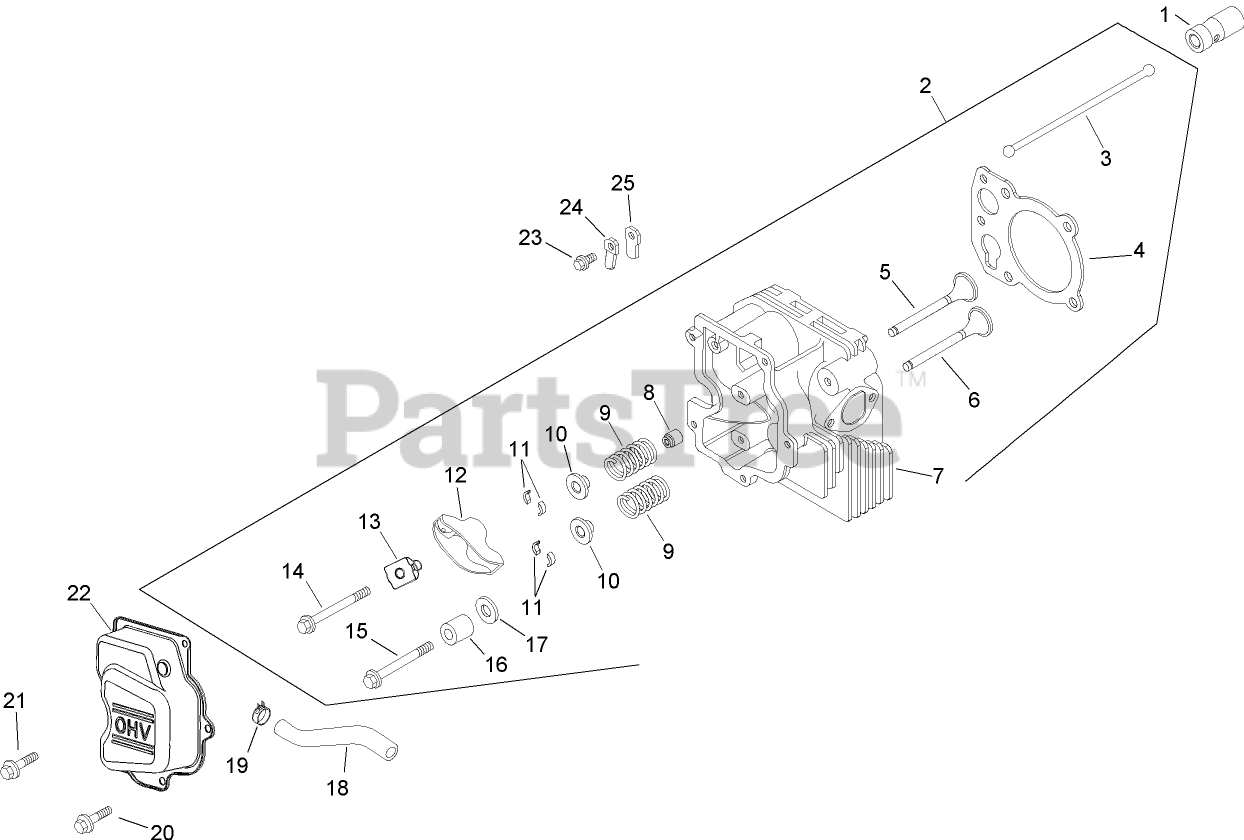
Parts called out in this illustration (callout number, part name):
1	Lifter-Valve
2	Cylinder Head Kit (Incl. Ref. No. 3-17)
3	Rod-Push
4	Gasket-Head, Cylinder
5	Valve-Intake (STD)
6	Valve-Exhaust (STD)
7	Head-Cylinder
8	SEAL-STEM, VALVE
9	Spring-Valve
10	CAP-SPRING, VALVE
11	RETAINER KIT
12	ARM-ROCKER
13	Pivot-Arm, Rocker
14	SCREW-FLANGE, THREAD FORMING (M6X1.0X16)
15	SCREW-FLANGE (M6X1.0X34)
16	Spacer
17	Washer-Flat (1/2)
18	Hose-Breather
19	CLAMP-HOSE, SPRING (1/2)
20	Screw-Flange, Hex (M10x1.5x37)
21	SCREW-FLANGE (M10X1.5X90)
22	Cover-Valve
23	SCREW-HHFTF (M5X.80X10)
24	RETAINER-REED
25	REED-BREATHER
